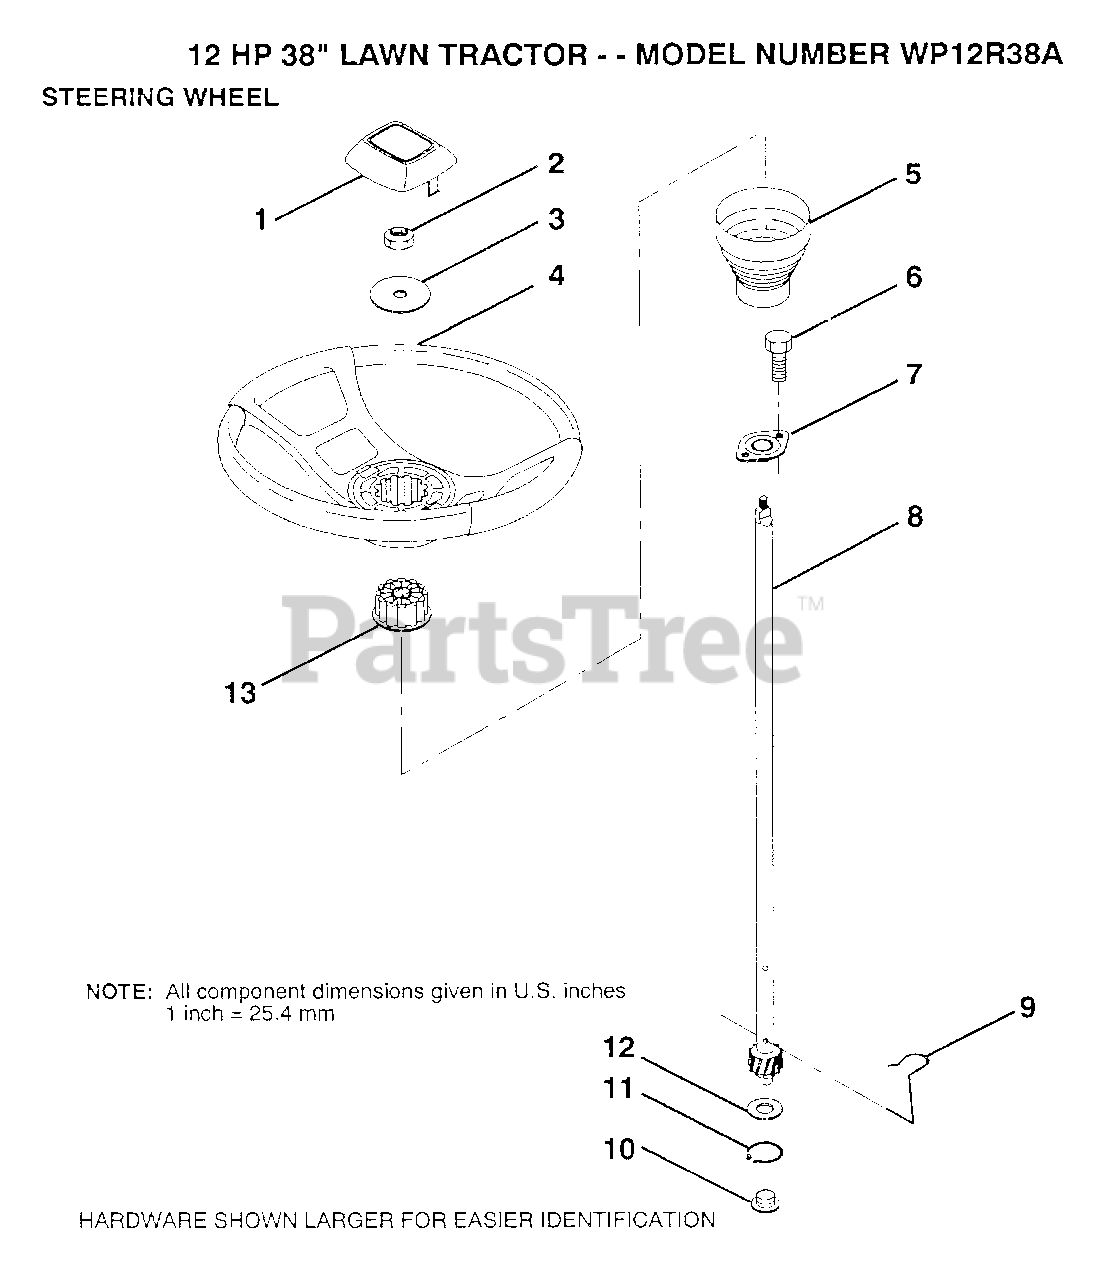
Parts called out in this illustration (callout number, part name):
1	ST WHL INSERT CAP
2	GRIPCO NUT
3	WASHER T
5	SLEEVE STEERING
9	STEERING CLIP
10	BUSHING STEER LWR
11	RING
12	WASHER LT
13	ADAPTER-WHEEL LT
